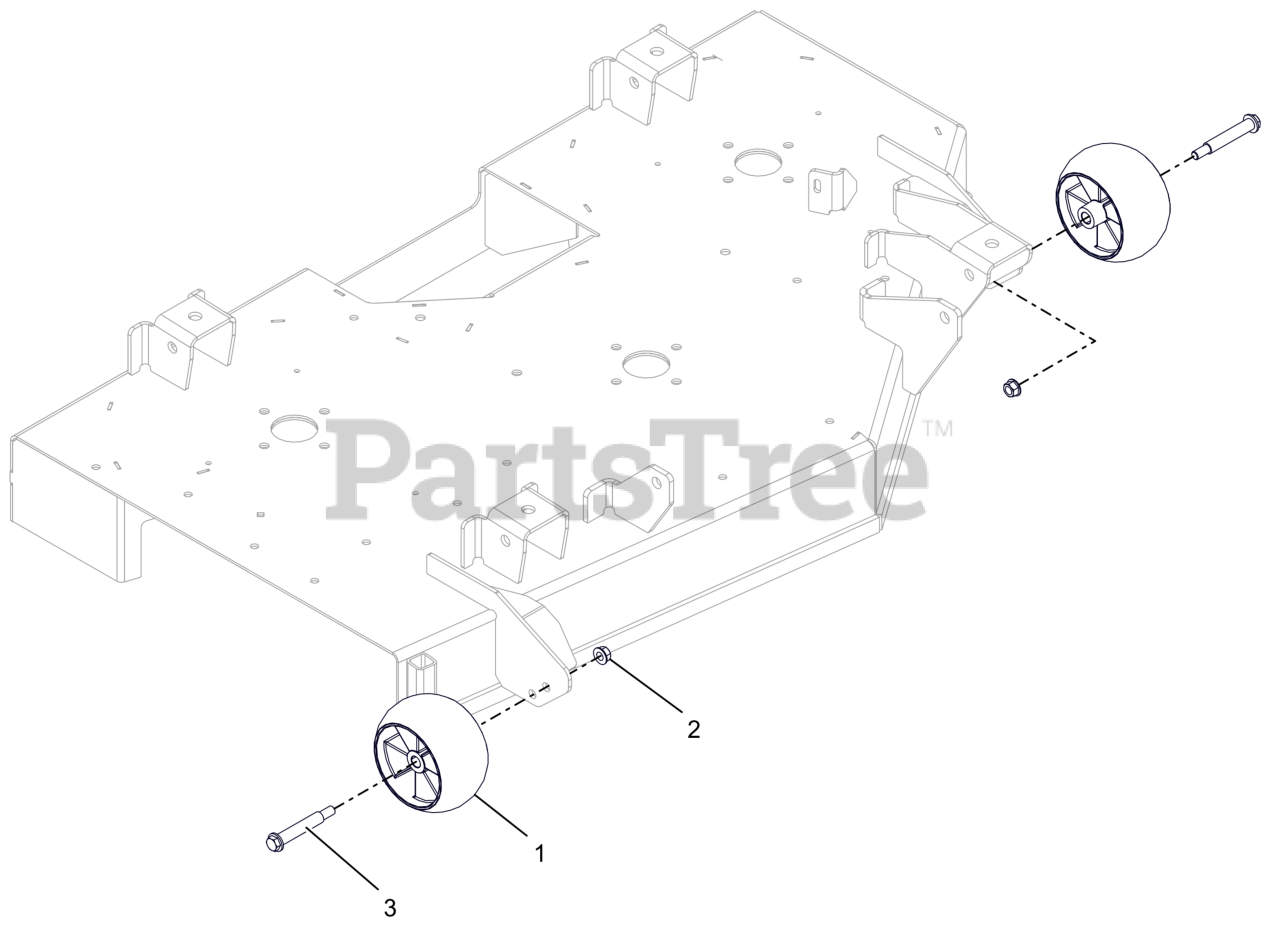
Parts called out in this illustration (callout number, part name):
1	ANTI-SCALP WHEEL - 5X OS
2	NUT-LK-CTR-FLG .375-16 GF ZCC
3	BLT-SHLDR .38-16X2.50 HWH G5
